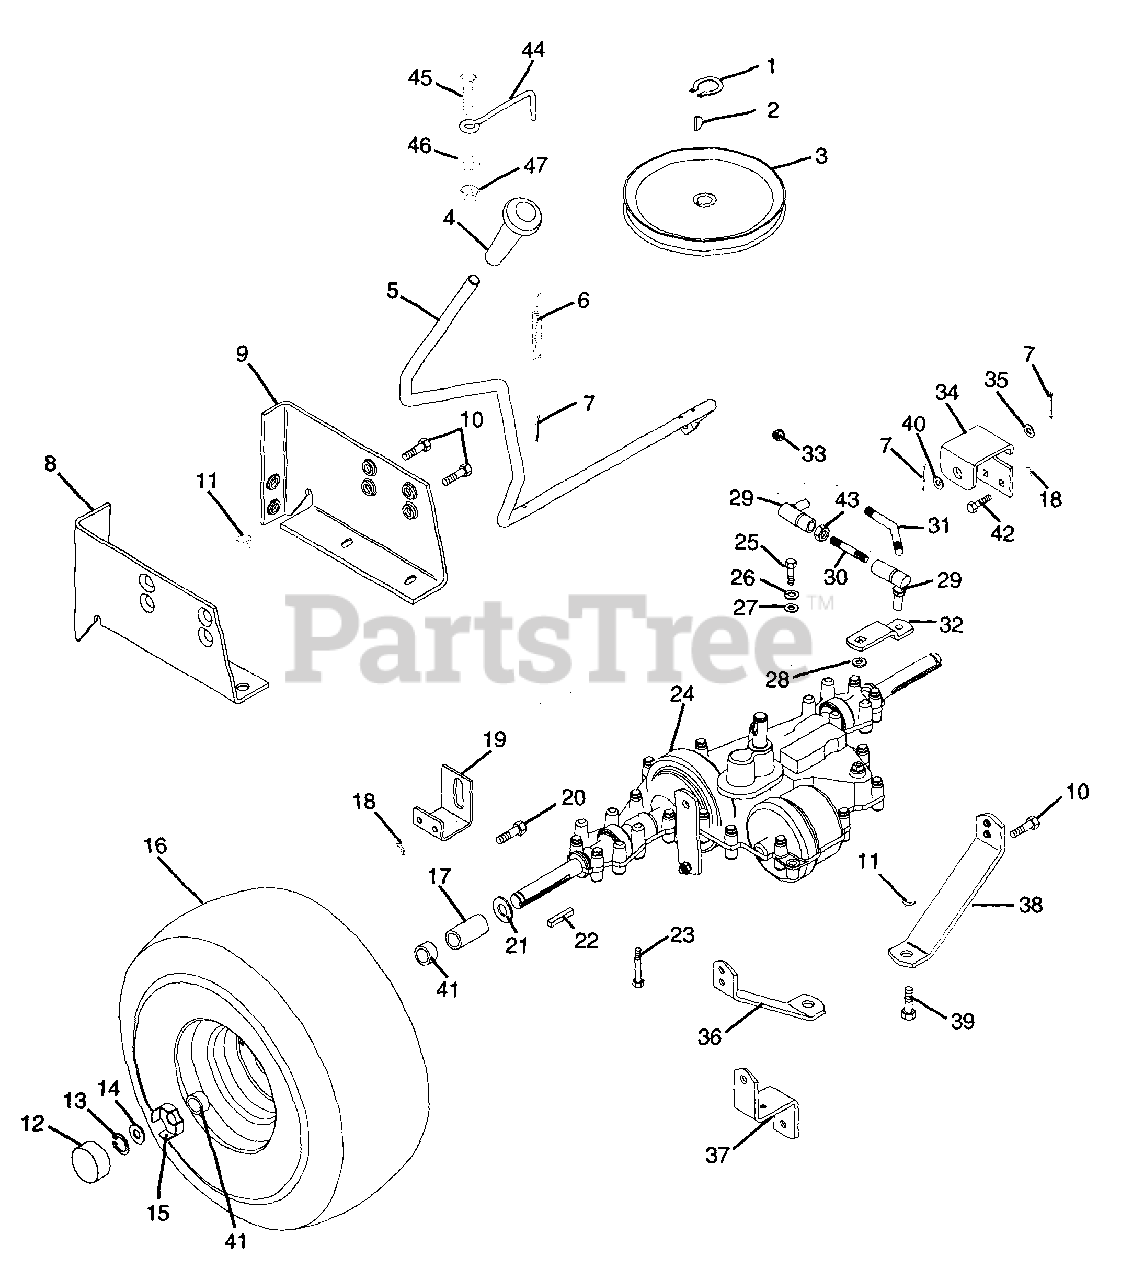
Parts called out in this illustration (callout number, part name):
1	RG-RTNG-EXT .625X.035
2	KEY-WDRF .188X.75X.313 SAE 9
3	PLY-TRANS 7.00X.626
5	SHIFT LEVER
6	SG-TENS .063X.44X1.56
7	PIN-COTR .12X1.0 PL
8	MOUNT- TRANS. RH
9	MOUNT- TRANS. LH
10	SCR-TAP .375-16X.75 HWH PL TR
11	NUT-LK-TOP .312-18 GR C PL
12	HUB CAP
13	RG-RTNG-EXT .750X.050
14	WSHR-FL-STL .755X1.375X.062 PL
15	SPINDLE CUP
16	T/WHL ASSY 20X8.00-8
16	RIM
16	TIRE 20X10-8 2P TS TL
16	T/WHL ASSY 18X6.50-8
16	RIM 8DC537WK CARLISLE
16	TIRE
17	BSHG-SLV .750X1.125X1.062
18	NUT-LK-NYL .250-20 PL
19	SHIFT GUIDE BRACKET
20	BLT-HEX .25-20X.75 PL GR2
21	WSHR-FL-STL .755X1.375X.062 PL
22	KEY-SQ .188X2.0X.188 SAE 8630
23	BLT-HEX .31-18X2.50 PL GR5
24	TRANSAXLE-GEAR 5-SPD 940-011A
24	TRANSAXLE-GEAR 6-SPD 930-051A
25	BLT-HEX .25-28X.75 PL GR5
26	WSHR-LK .250X.077 HVY PL
27	WSHR-FL-STL .328X1.0X.094 PL
28	WSHR-FL-STL .505X1.000X.062
29	SNAP IN BALL JOINT
30	SHIFT LINK
31	SHIFT LINK
32	SHIFT ARM
33	NUT-LK-CTR .312-24 PL
34	SHIFT PIVOT BRACKET
35	WSHR-FL-STL .520X.810X.033
36	TORQUE STRAP- R
37	TORQUE STRAP- R
38	TORQUE STRAP- L
38	TORQUE STRAP- LH
39	BLT-HEX .31-18X2.00 PL GR5
40	WSHR-FL-STL .520X.827X.062 YZ
41	SPACER .760X1.000X.575
42	BLT-RDHDSQNK .25-20X.75
43	NUT-JAM .312-24 PL
44	FINGER - BELT
45	BLT-HEX .31-18X.75 PL GR5
46	WSHR-FL-STL.344X.688X.065PL
47	NUT-LK .312-18 GR A PL
